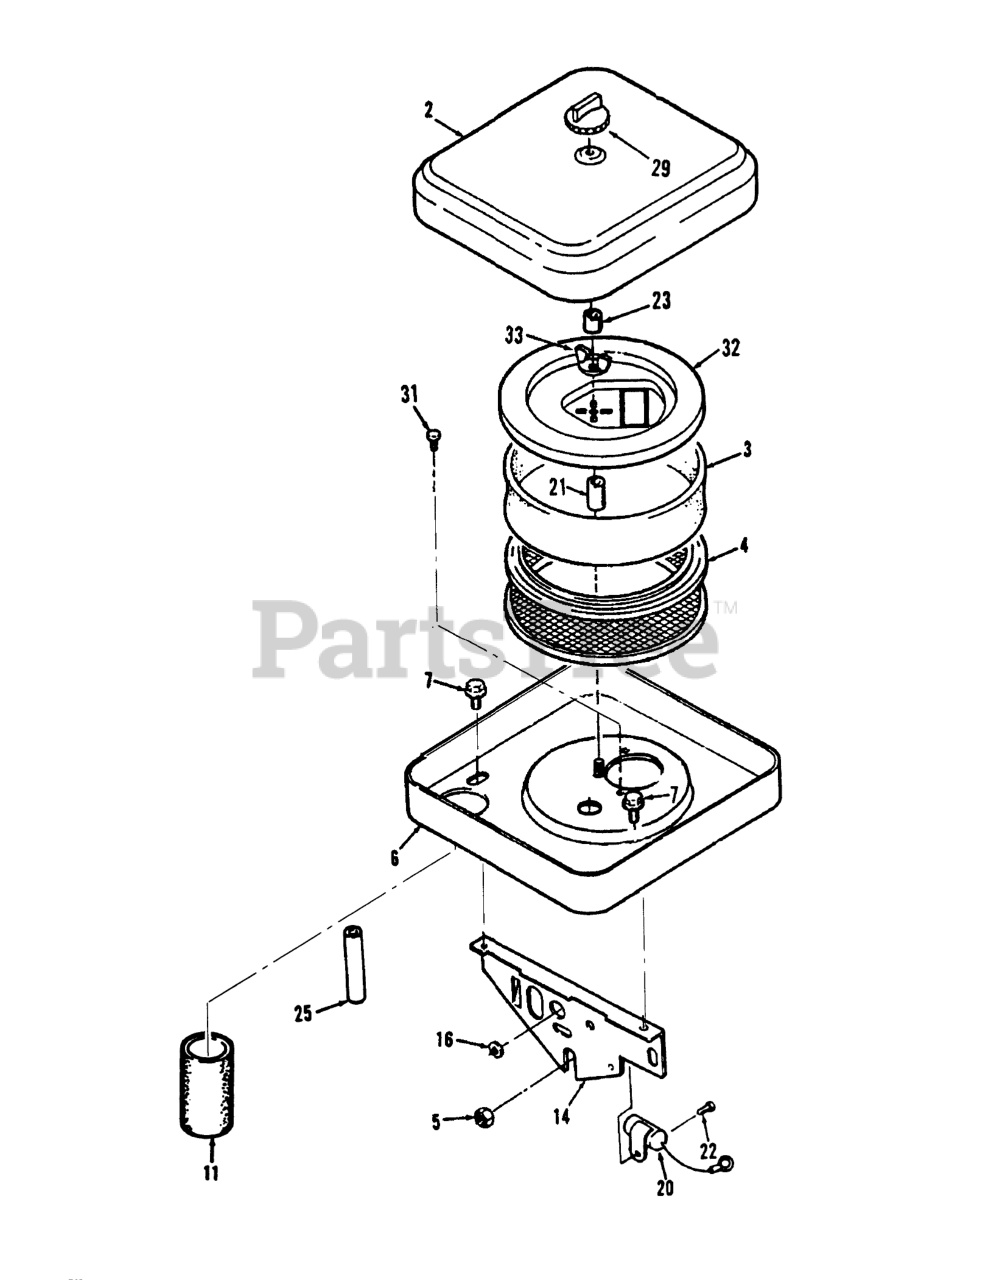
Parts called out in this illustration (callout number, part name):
2	AIR-CLEANER COVER
3	AIR CLEANER ELEMENT
4	Stationary Guard
6	AIR-CLEANER HOUSING
7	SCREW-TAPPING
11	AIR INTAKE TUBE
14	SUPPORT-AIR CLEANER
16	Grommet
20	Capacitor (300 VD)
22	SCREW #10-32 X 5/8
23	SPACER-RUBBER
25	BREATHER TUBE
29	KNOB-TOOL LESS
31	MACHINE SCREW
32	Cover-Element
33	1/4-20 WING NUT
